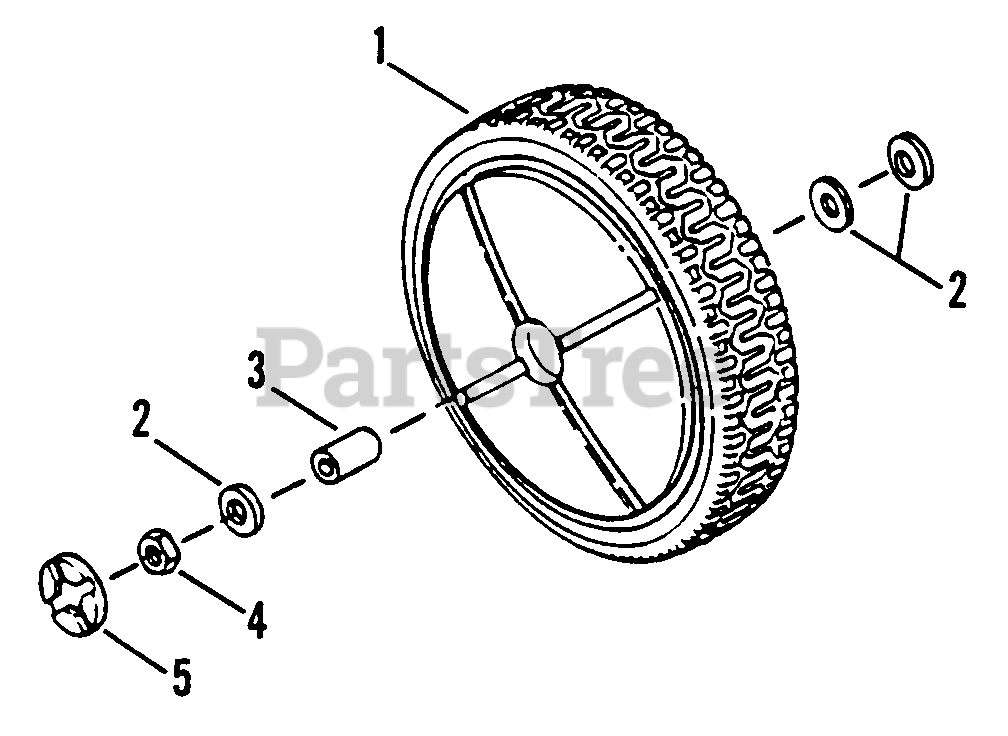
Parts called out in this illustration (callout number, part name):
1	WHEEL, Front, 8 x 1.75" Plastic
2	WASHER, 7/16 x 1" O.D. Flat
3	BUSHING, Axle
4	NUT, 7/16-20 Hex
5	PLUG, Wheel
